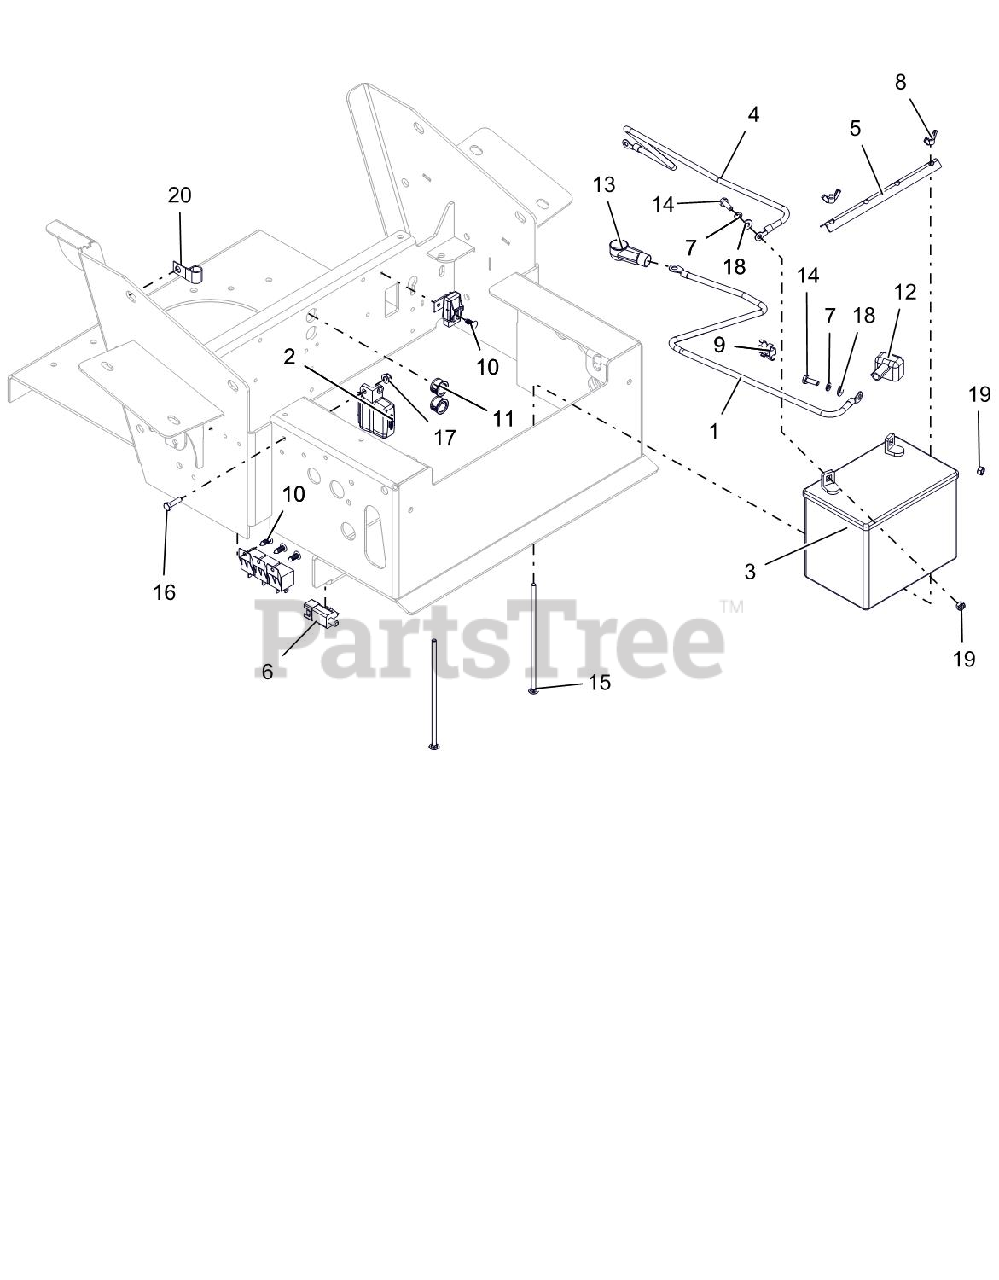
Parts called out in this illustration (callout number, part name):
1	CABLE, POS W/(2) 5/16 RING 30.0 LG
2	HARNESS, PT100 WIRE
3	BATTERY, 300 CCA 10U1L
4	CABLE, NEGATIVE BATTERY 24"
5	HOLD DOWN - BLK
6	SWITCH, SNAP IN -N.O./N.O
7	WSHR-LK .25X.062 REG YWZC
8	NUT-LOCKING WING 1/4-20
9	CLIP, T, .31-.38
10	RIVET, .25 NYLON PANEL
11	BUSH, PANEL SNAP .687X.875X.56
12	INSULATOR
13	BOOT, .65 ID POS
14	BOLT, HEX 0.25-20X0.75 GR5
15	BOLT, CARRIAGE 0.25-20X7.5 GR5
16	BOLT, HEX 0.25-20X1 GR5
17	NUT-LK-NYL-FLG .25-20 YWZC
18	WSHR-FL-STL.281X.62X.065 YWZC
19	NUT-HEX .25-20 YWZC
